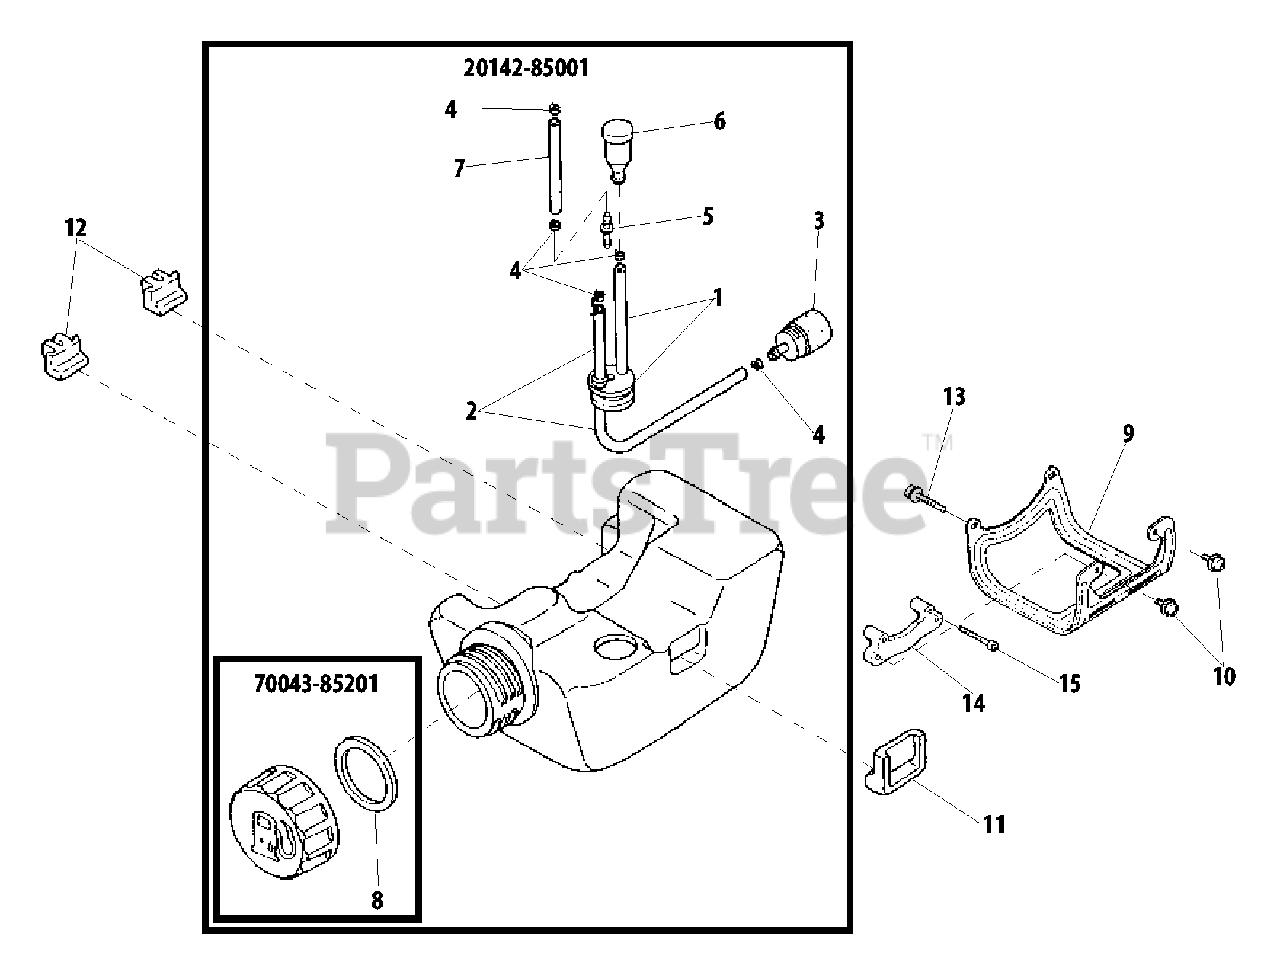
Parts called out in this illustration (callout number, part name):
1	GROMMET
2	PIPE, FUEL
3	FILTER, FUEL 125-528
4	CLIP Ø6
5	CONNECTOR, PIPE
6	VENT ASSY
7	PIPE, FUEL RETURN
8	GASKET, FUEL CAP
9	GUARD, METAL FUEL TANK
10	SCREW M5×12
11	CUSHION, FUEL TANK
12	CUSHION, FUEL TANK
13	SCREW M5×30
14	BRACKET
15	BOLT M4×30
20142-85001	TANK ASSY, FUEL
70043-85201	CAP ASSY, FUEL
